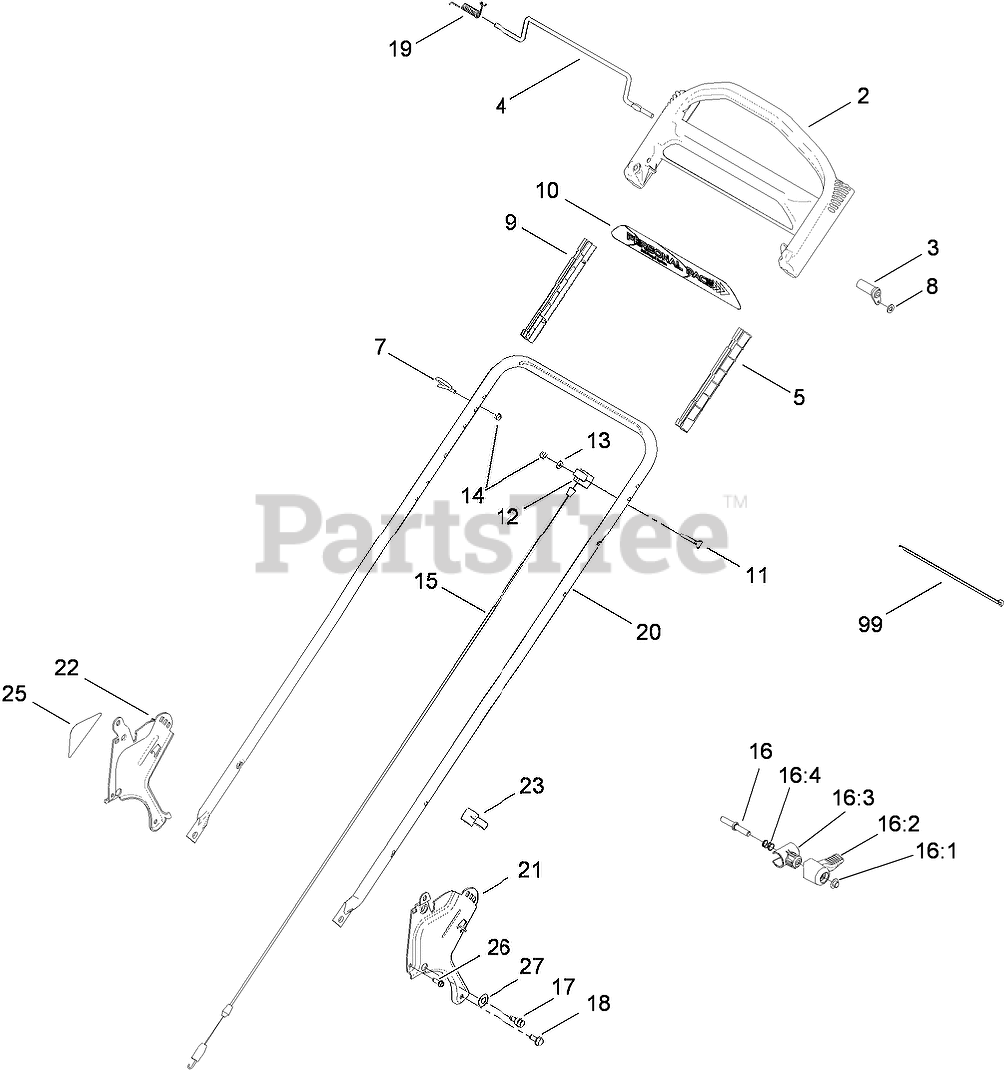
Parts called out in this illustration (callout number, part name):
2	HANDLE-CONTROL
3	LEVER-TRACTION
4	BAR-CONTROL, TRACTION
5	GUIDE-LH
7	GUIDE-ROPE
8	WASHER-PLAIN
9	GUIDE-RH
10	DECAL-HANDLE
11	SCREW-HH
12	ANCHOR-CABLE
13	WASHER-FLAT
14	NUT-LOCK, NI
15	CABLE-TRACTION
16	QUICK RELEASE ASM
16:1	NUT-PUSH
16:2	LEVER
16:3	ANCHOR-SPRING
16:4	SPRING-COMPRESSION
17	BOLT-SHOULDER
18	SCREW-HWHTF
19	Spring-Torsion
20	HANDLE
21	BRACKET-HANDLE, LH
22	BRACKET-HANDLE, RH
23	Guide-Cable
25	DECAL-INSTRUCTION
26	SCREW-HWHTF
27	WASHER-SPRING, CONICAL
99	TIE-CABLE
